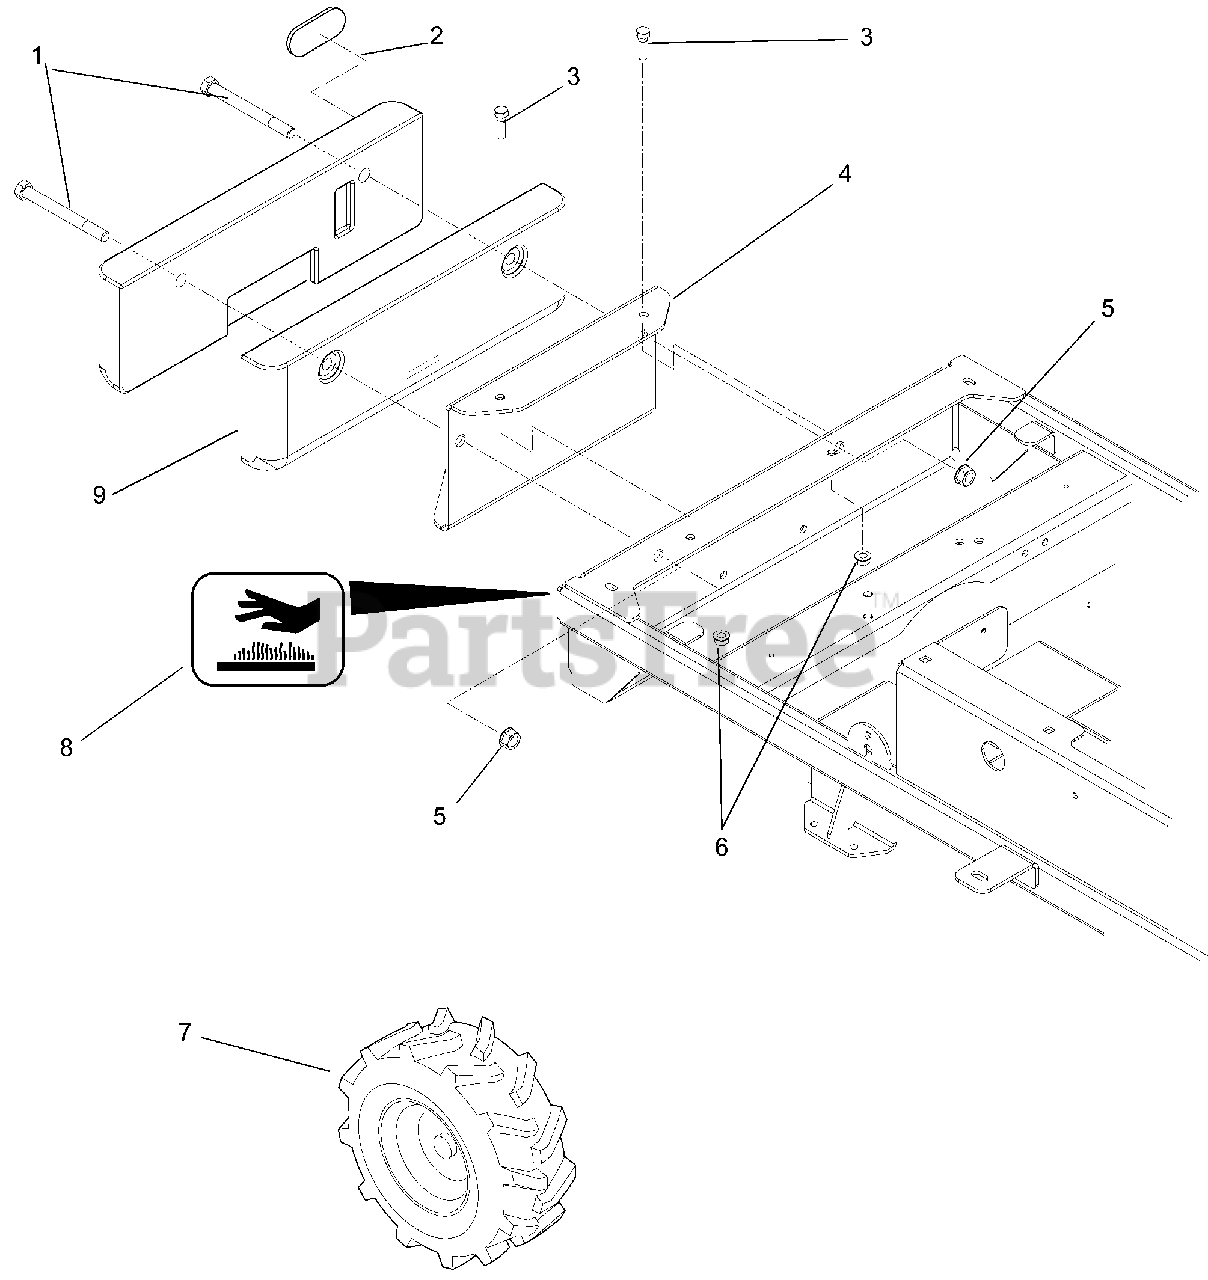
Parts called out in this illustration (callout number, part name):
1	Bolt, Hex .50-13 x 5.00 Grade 5
2	Reflector
3	Bolt, Hex .38-16 x 1.25 Grade 5
4	Bracket, Weight
5	Nut, Top-Locking Flange .50-13
6	Nut, Top-Locking Flange .38-16
7	Assembly, Wheel and Tire, Snow Hog 18 x 6.5
8	Decal, Hot Surface
9	Weight, Cast Iron
47788	(Agri-Fab Part Number)
